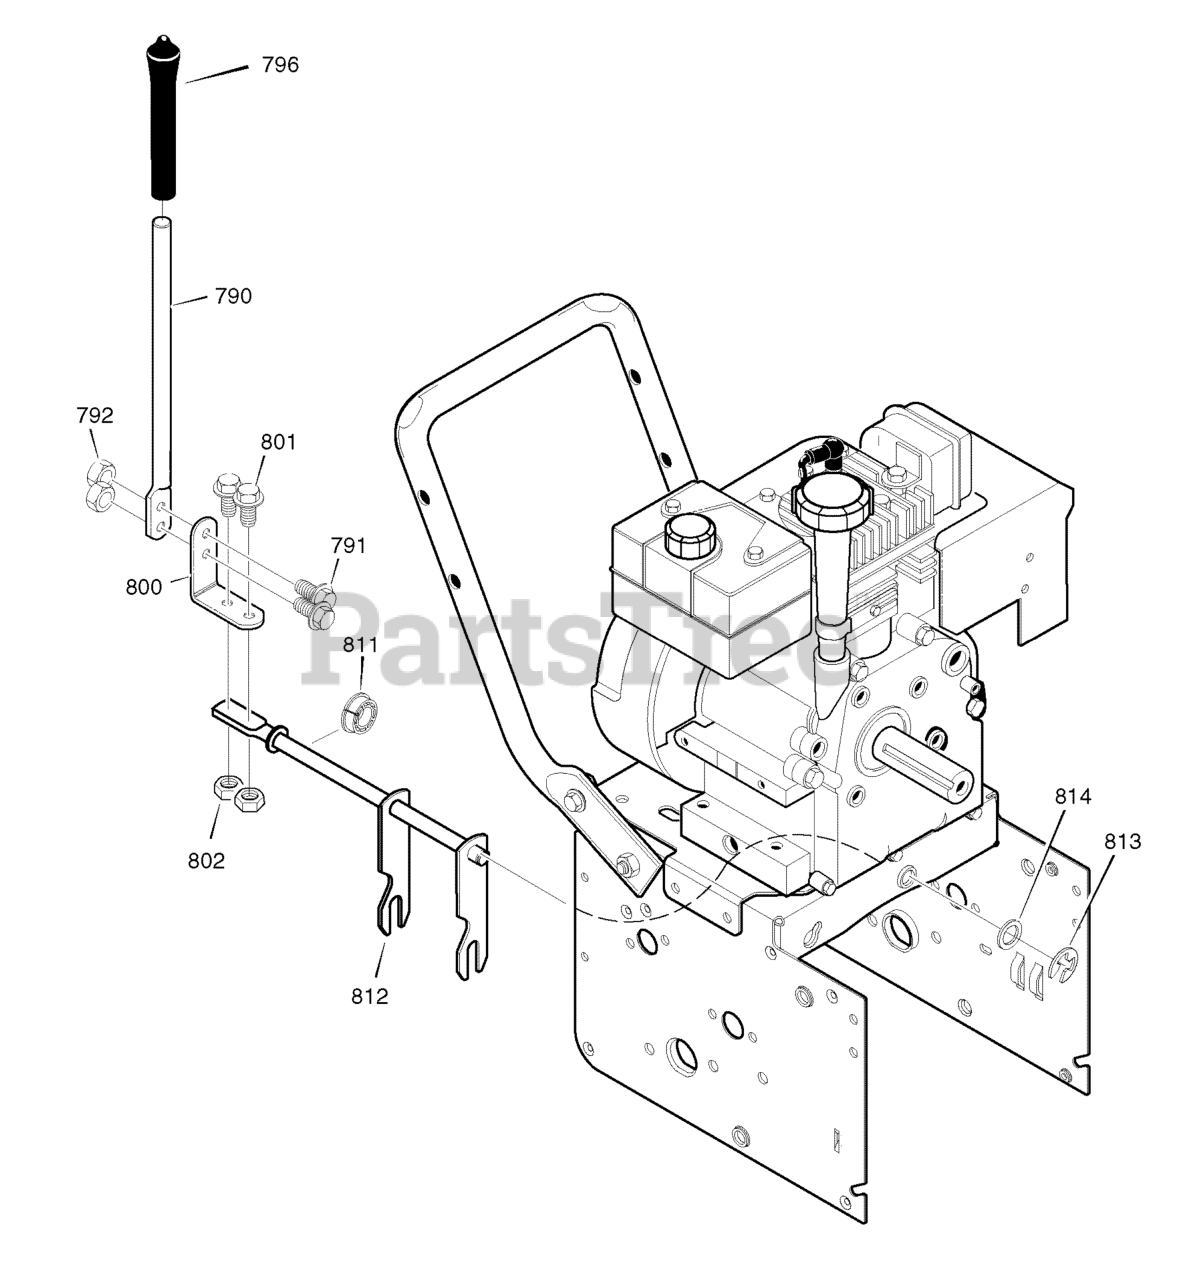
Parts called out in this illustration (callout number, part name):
790	ROD, SHIFT
791	SCREW, 1/4-20 x 3/4
792	NUT, 1/4-20
796	KNOB, Slip
800	LEVER, Spring
801	SCREW, 1/4-20 x 3/4
802	NUT, 1/4-20
811	BEARING, Flanged
812	ROD ASSEMBLY, Speed Select
813	RETAINER, Ring
